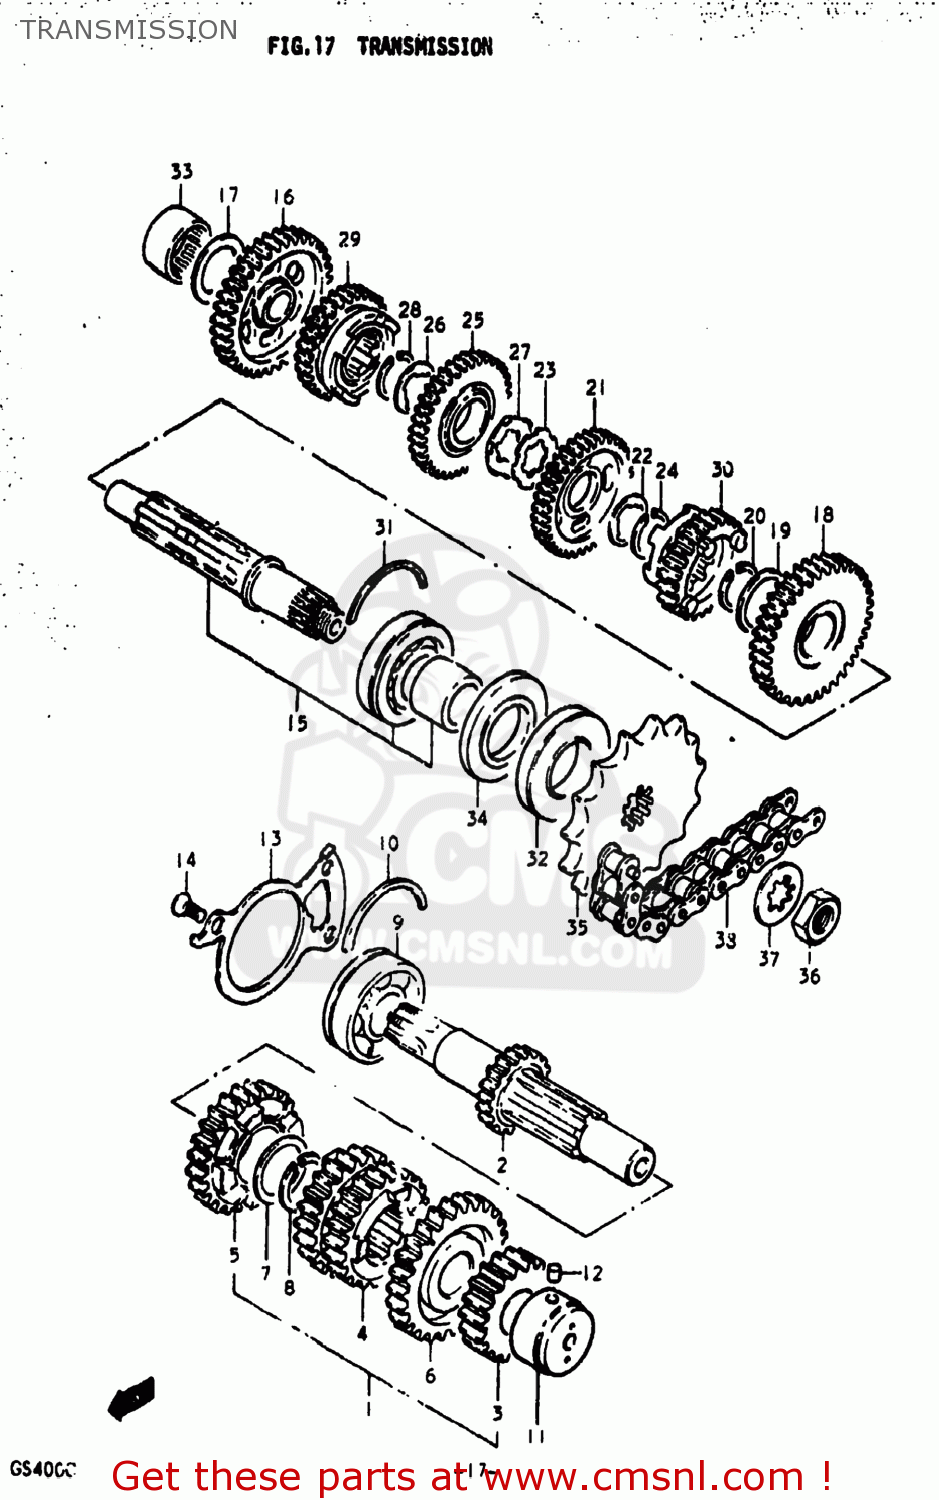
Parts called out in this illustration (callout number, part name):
1	SHAFT,COUNTER
2	SHAFT,COUNTER
3	GEAR,2ND DRIVE(NT:18)
4	GEAR,THIRD DRIVE
5	GEAR,FIFTH DRIVE
6	GEAR,SIXTH DRIVE
7	WASHER
8	CIRCLIP
9	BEARING(25X62X17)
10	C-RING
11	ROLLER BEARING (20X34X2
12	PIN
13	PLATE,COUNTERSHAFT BEARING
14	SCREW
15	SHAFT,DRIVE
16	GEAR,FIRST DRIVEN
17	WASHER
18	GEAR,SECOND DRIVEN
19	WASHER
20	CIRCLIP
21	GEAR,THIRD DRIVEN
22	WASHER,LOCK
23	WASHER,LOCK
24	CIRCLIP
25	GEAR,FOURTH DRIVEN
26	WASHER,LOCK
27	WASHER
28	CIRCLIP
29	GEAR,FIFTH DRIVEN
30	GEAR,SIXTH DRIVEN
31	C-RING
32	OIL SEAL
33	ROLLER BEARING (20X34X1
34	SEAL,OIL(32X62X5.5)
35	SPROCKET,ENGINE(NT:16)
36	NUT
37	WASHER
38	CHAIN ASSEMBLY,DRIVE
